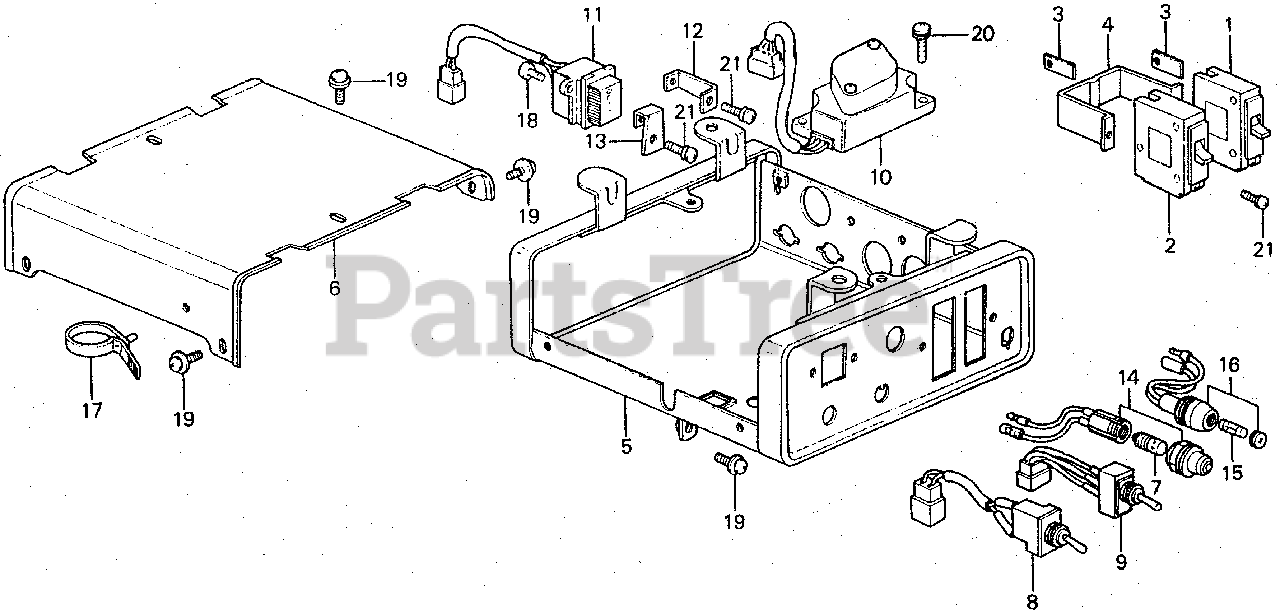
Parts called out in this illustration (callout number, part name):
1	BREAKER, CIRCUIT (18A) (NOT AVAILABLE)
2	BREAKER, CIRCUIT (37A)
3	TERMINAL, BREAKER
4	SUPPORT, BREAKER (NOT AVAILABLE)
5	BOX, CONTROL *R8* (BRIGHT RED)
6	COVER, CONTROL BOX (UPPER) *R8* (BRIGHT RED)
6	COVER, BOX (UPPER) *R8* (BRIGHT RED)
7	BULB, DASH (24V-2W)
8	SWITCH ASSY., IDLE CONTROL (NOT AVAILABLE)
9	SWITCH ASSY., ENGINE
10	CONTROL UNIT (NOT AVAILABLE)
11	METER, FREQUENCY (NOT AVAILABLE)
12	HOLDER A, FREQUENCY METER
13	HOLDER B, FREQUENCY METER
14	SOCKET ASSY., PILOT LAMP
15	FUSE (15A)
16	HOLDER ASSY., FUSE
17	STRAP B, CABLE (125MM) (BLUE)
18	SCREW, PAN (3X8)
19	SCREW-WASHER (5X12)
20	SCREW-WASHER (6X16)
21	SCREW-WASHER (4X12)
